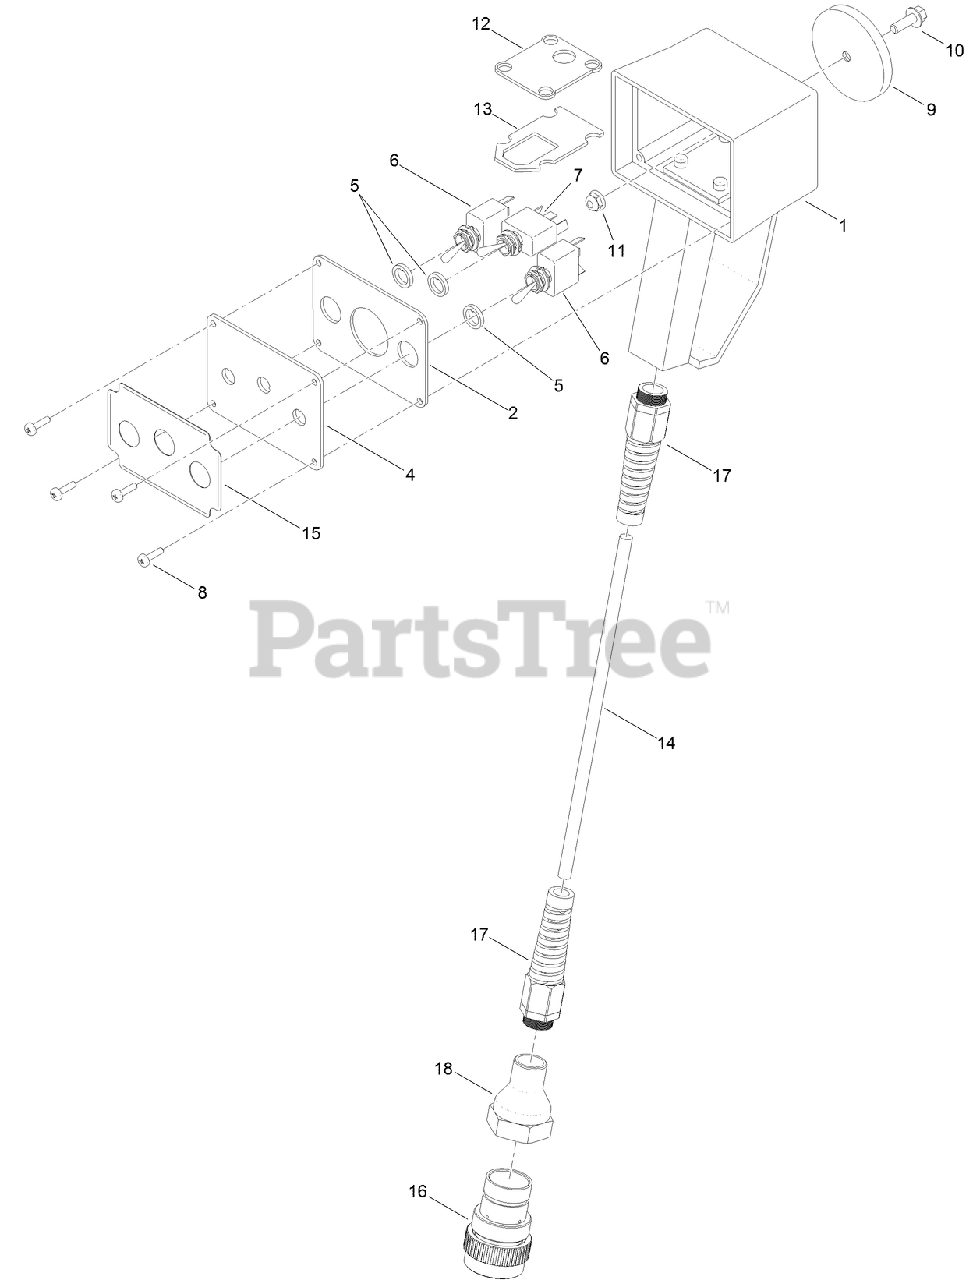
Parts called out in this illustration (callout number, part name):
1	ENCLOSURE-HANDHELD
2	GASKET-ENCLOSURE
4	PLATE-LIFE JACKET
5	SEAL-SWITCH
6	SWITCH
7	SWITCH
8	SCREW-PPH
9	MAGNET-CERAMIC, ENCASED
10	SCREW-HHF
11	NUT-HF
12	GASKET-HANDLE, INNER
13	GASKET-HANDLE, OUTTER
14	CABLE-LIFEJACKET
15	DECAL-LIFEJACKET
16	CONNECTOR-DEUTSCH, 14F
17	GRIP-CORD
18	COUPLER
